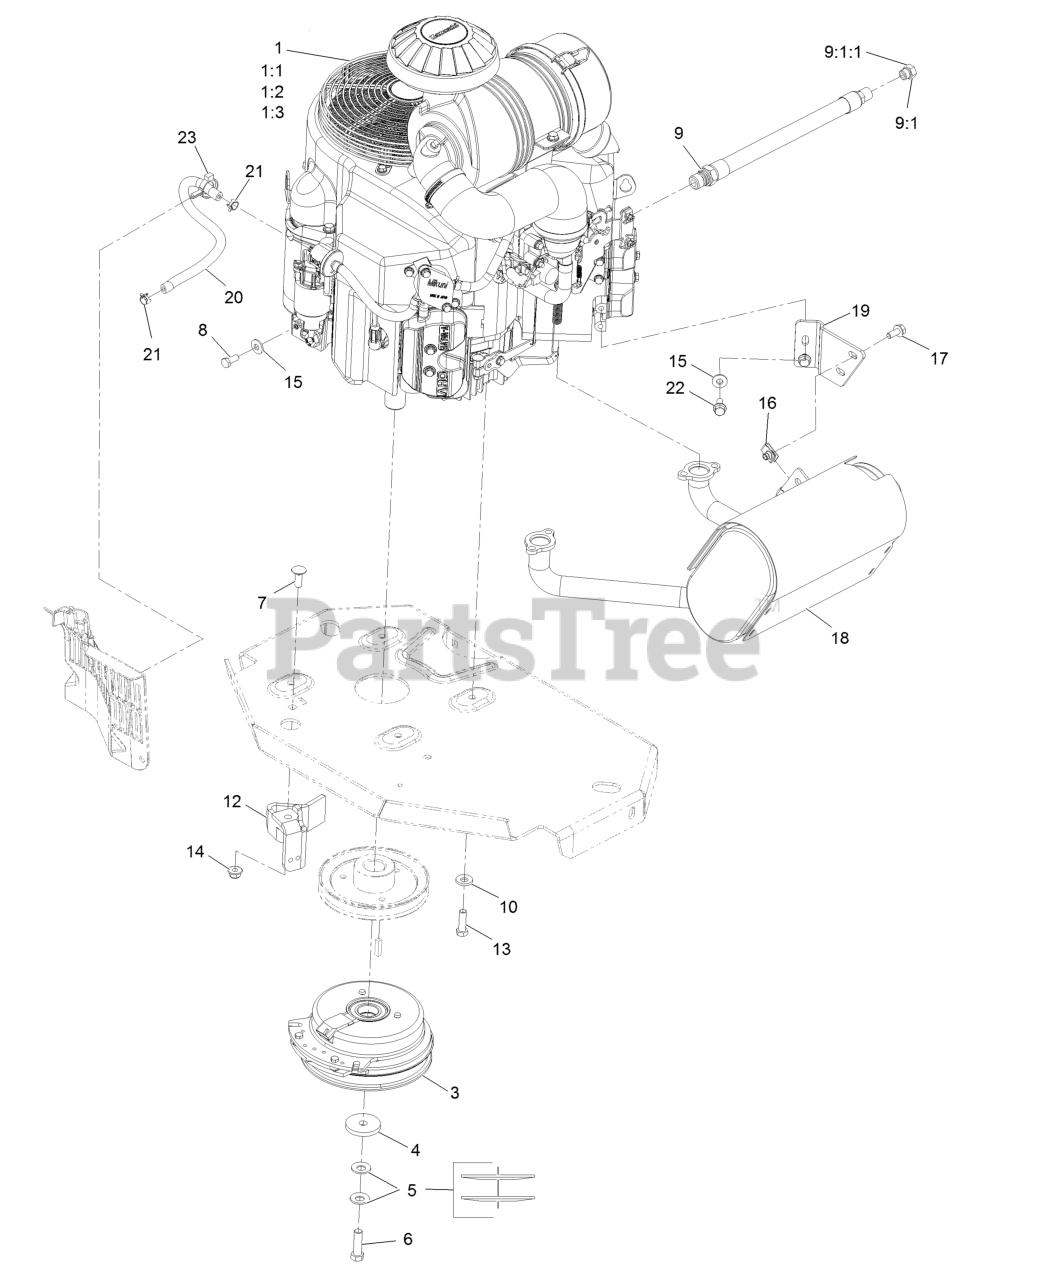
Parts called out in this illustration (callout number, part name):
1:1	Kawasaki 49065-2078 Engine Oil Filter
1:2	Kawasaki 11013-7044 Engine Air Filter
1:3	Kawasaki 11013-7045 Safety Filter
3	CLUTCH KIT
4	WASHER-CLUTCH
5	WASHER-SPRING
6	SCREW-HH 7/16-20 X 1 1/2 W/LOCTITE
7	SCREW-CARR
8	SCREW-HH
9	ENGINE OIL DRAIN HOSE ASM
9:1	PLUG-HH
9:1:1	O-RING
10	WASHER-BELLEVILLE
12	CLUTCH-ANCHOR
13	SCREW-HH
14	NUT-HF, NI
15	WASHER-SPRING
17	SCREW-HHF
18	MUFFLER
19	BRACKET-MUFFLER
20	HOSE-FUEL
21	CLAMP-HOSE
22	SCREW-HHF
23	CLAMP-HOSE
